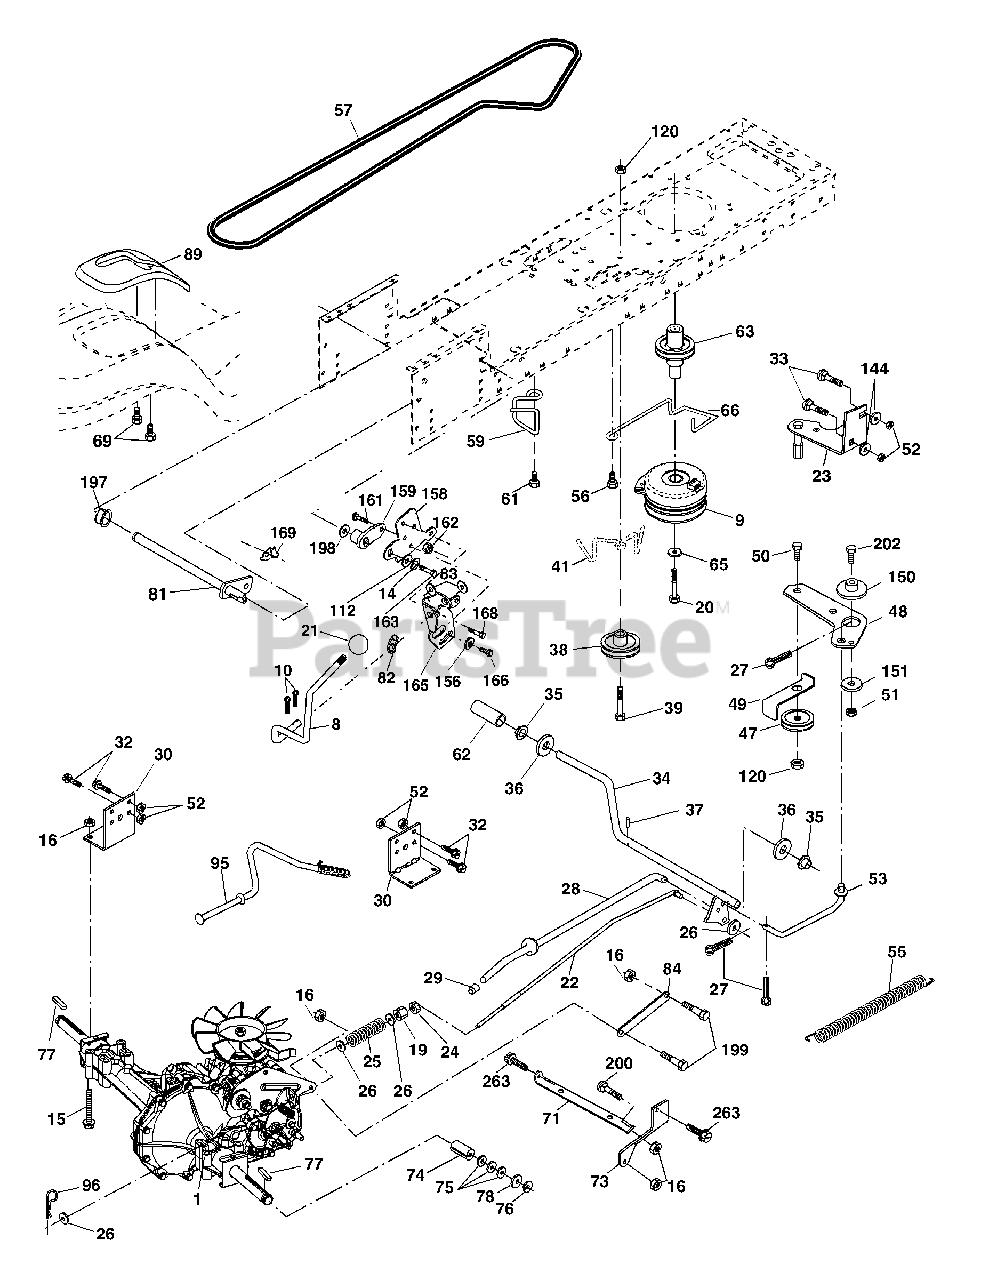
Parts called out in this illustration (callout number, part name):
8	Rod Shift Fend.
9	Clutch Electric
10	Pin Cotter 1/8 x 1
14	Washer Lock Hvy 1/4
15	Bolt Hex Flghd 5/16-18 Gr. 5
16	Nut Lock Hex W/Ins. 5/16-18 unc
17	Washer 1-1/2 x 15/32 x .250
19	Nut Lock Hex W/Wsh 3/8-16 unc
20	Bolt Hex 7/16-20 x 4-1/4 5 Ga. 1.38
21	Knob
22	Rod, Brake
23	Bracket Asm Anti-Rotation
24	Nut, Hex Jam 3/8-16 unc
25	Spring, Brake Rod
26	Washer
27	Pin Cotter 1/8 x 3/4 CAD.
28	Rod, Parking Brake
29	Knob Brake Parking
30	Bracket, Transaxle
32	Bolt Hex Hd 5/16-18 unc x 3/4
33	bolt Rdhd Sqnk 5/16-18 unc x 3/4
34	Shaft, Foot Pedal
35	Bearing, Nylon
36	Washer
37	Pin, Roll
38	Pulley, Composite
39	Bolt Rdhd 3/8-16 unc x 2-3/4 Gr. 5
41	Keeper, Belt Idler Flat
47	Pulley, Idler, V-Groove
48	Bellcrank Clutch Grnd Drw Stl
49	Retainer, Belt
50	Bolt
51	Nut Crownlock 3/8-16 unc
52	Nut, Crownlock 5/16-18 unc
53	Link, Clutch
55	Spring, Return, Clutch
56	Screw 3/8-16 x 1-1/4
57	V-Belt, Ground Drive
59	Keeper, Center Span
61	Screw 3/8-16 x .875
62	Cover, Pedal
63	Pulley, Engine
65	Washer
66	Keeper Belt Engine
69	Screw Hex Wsh H-Lo 1/4-1/2 unc
71	Strap Torque LH
73	Strap Torque RH
74	Spacer, Axle
75	Washer 25/32 x 1-1/4 x 16 Ga.
76	E-Ring
77	Key, Square
78	Washer 25/32 x 1-5/8 x 16 Ga.
81	Shaft Assy. Cross Taper
82	Spring Torsion
83	Washer 17/32 x 3/4 x 16 Ga.
84	Link Transaxle
89	Console, Shift
95	Rod Bypass
96	Retainer Spring 1" Zinc/Cad
112	Washer 9/32 x 3/4 x 10 Ga.
120	Nut Lock Flg 3/8-16 unc
144	Washer 11/32 x 5/8 x 16 Ga.
150	Spacer Retainer
151	Washer 13/32 x 2 x 10 Ga.
156	Washer 5/16 ID x 1.0 x .125
158	Bracket Shift Mount
159	Hub Shift
161	Bolt Rdhd Sqnk 1/4-20 x 3/4 Gr. 5
162	Nut Crownlock 1/4-20 unc
163	Bolt Hex Fin 1/4-20 unc x 1 Gr. 5
165	Bracket Pivot Lever
166	Screw 5/16-18 x 5/8
168	Bolt Shoulder 5/16-18 x .561
169	Plate Fastener Cross Shf.
197	Nyliner Snap-in 5/8 ID
198	Washer Nyl 7/8 ID x .105"
199	Bolt Shoulder 5/16-18 unc
200	Bolt Rdhd Sqnk 5/16-18 unc x 1
202	Bolt Carr Sh 3/8-16 x 1-3/4 Gr. 5
254	Screw 3/8-16 x 1
263	Screw 3/8-16 x .75
